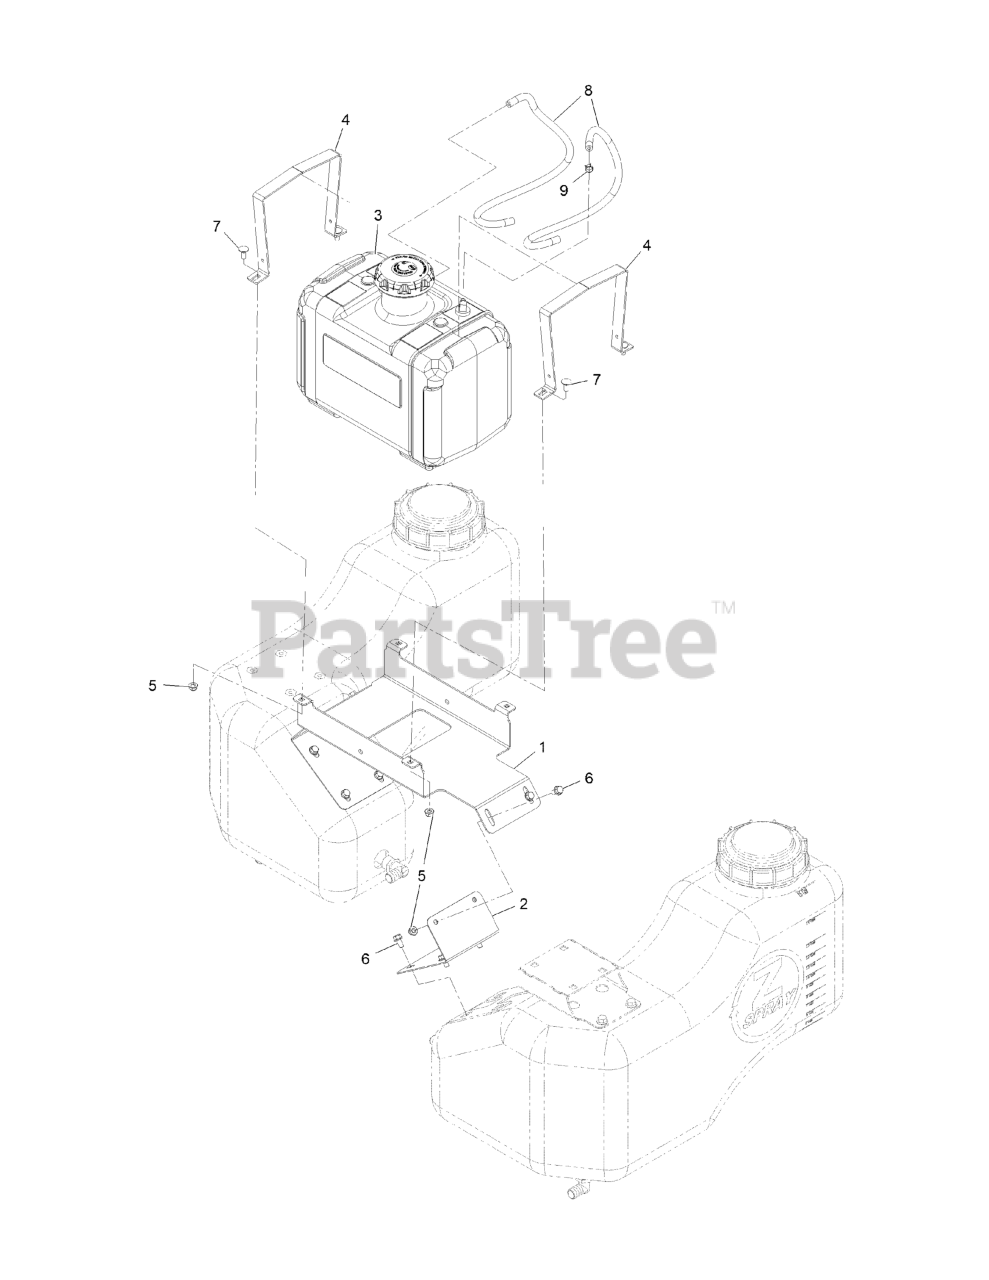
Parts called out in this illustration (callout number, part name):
1	Mount-Tank, Fuel
2	BRACKET-SUPPORT, GAS TANK
3	ASM-Tank, 5 Gal.
4	Strap, Gas Tank
5	Nut-Hex Flange
6	Screw-HHF
7	SCREW-CARR
8	HOSE-FUEL
9	CLAMP-HOSE
